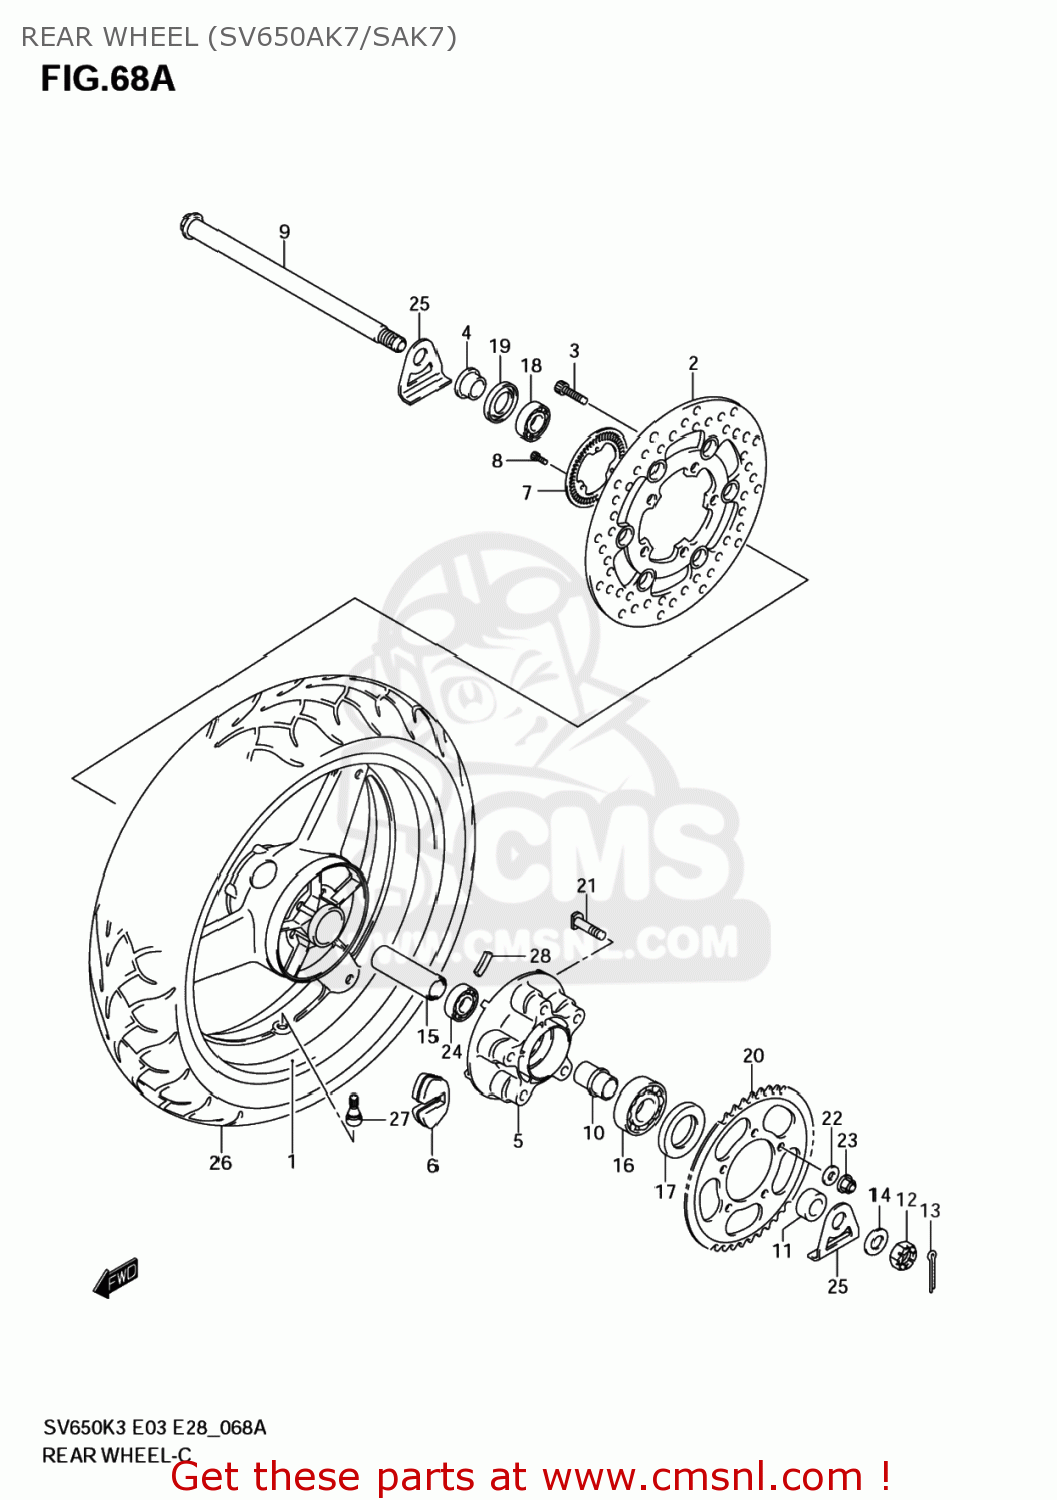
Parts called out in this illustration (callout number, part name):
1	WHEEL,RR(17M/CXMT4.50)
2	DISC,RR BRAKE
3	BOLT(8X33)
4	SPACER,RR AXLE,R
5	DRUM,RR SPROCKET MOUNTING
6	ABSORBER,RR HUB SHOCK
7	RING,SPEED SENSOR RR(50T)
8	BOLT
9	AXLE,RR
10	RETAINER,RR HUB BEARING
11	SPACER,RR AXLE,L
12	NUT
13	PIN, COTTER
14	WASHER(18.5X28X2.6)
15	SPACER(20.5X28X88)
16	BEARING(20X47X14)
17	SEAL,OIL(28X47X7)
18	BEARING(25X62X17)
19	SEAL,OIL(35X62X8)
20	SPROCKET,RR(NT:45-525)
21	BOLT(10X47)
22	WASHER (10.5X22X2.3)
23	NUT
24	BEARING
25	WASHER,CHAIN ADJUSTER
26	TIRE,RR(160/60 ZR17M/C 69W)
27	VALVE ASSY,WHEEL RIM(TR412)
28	BALANCER,WHEEL(10G)
